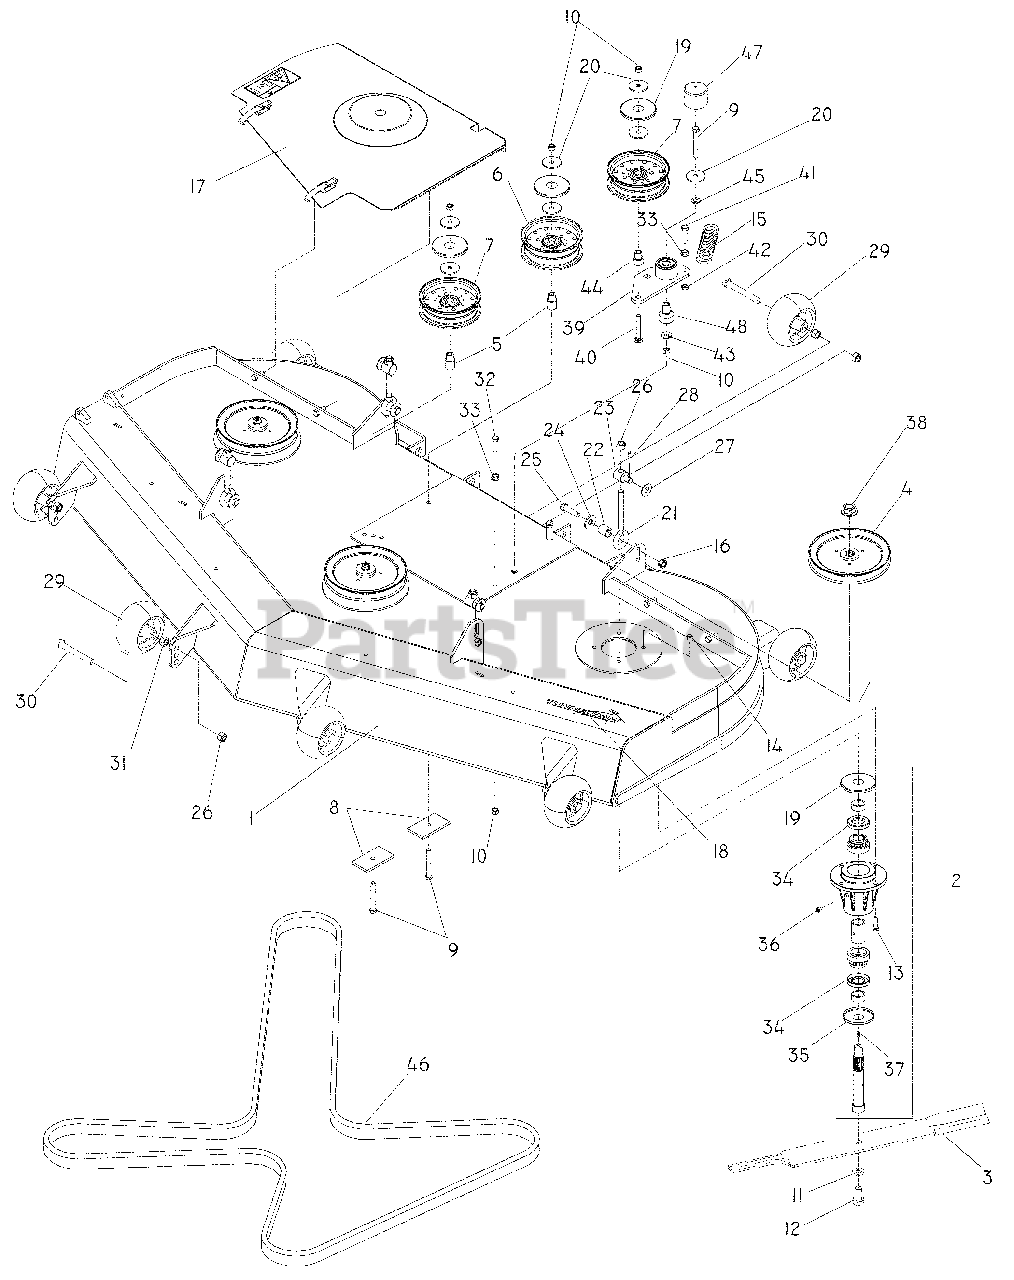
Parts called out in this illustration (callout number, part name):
1	DECK W/DECALS
2	HOUSING ASM
3	BLADE - 25"
5	IDLER BUSHING
6	IDLER PULLEY
7	IDLER PULLEY
8	PAD, PAINTED
9	HCS 3/8-16 x 3
10	NUT 3/8-16 HEX NYLOC
11	WASHER 5/8 SLW
12	HCS 5/8-18 x 1¼
13	HCS 5/16-18 x 1¼
14	NUT 5/16-18 HEX NYLOC
16	NUT 7/16-14 HEX CTRLK GR A
17	72 BELT SHIELD ASM - RT
18	DECAL, TUNNELRAM 8"
19	TOP DUST CAP
20	WASHER - 3/8 SPECIAL
24	SPRING WASHER
25	HCS 7/16-14 x 1¾
26	NUT ½ -13, NYLOC
27	WASHER, ½ STD FLT
28	PIN COTTER 1/8 x 1
29	WHEEL, GAUGE
30	HHB ½-13 x 4
31	NUT ½-13 HEX
32	HCS 3/8-16 x 1¼
33	NUT 3/8-16 HEX WHIZLK
34	SHAFT SEAL
35	BOTTOM DUST CAP
36	GREASE POPPET
38	NUT FLANGE ¾-16
39	ARM, IDLER - W/BEARINGS
40	RHSNB 3/8-16 x 2¾
41	HCS 3/8-16 x 1½ GR 8
42	NUT 3/8-16 HEX JAM
43	WASHER, 3/8 FLAT STD
44	BUSHING, IDLER
45	WASHER, 3/8 SAE FLT
47	CAP, VINYL
48	PIVOT BEARING
